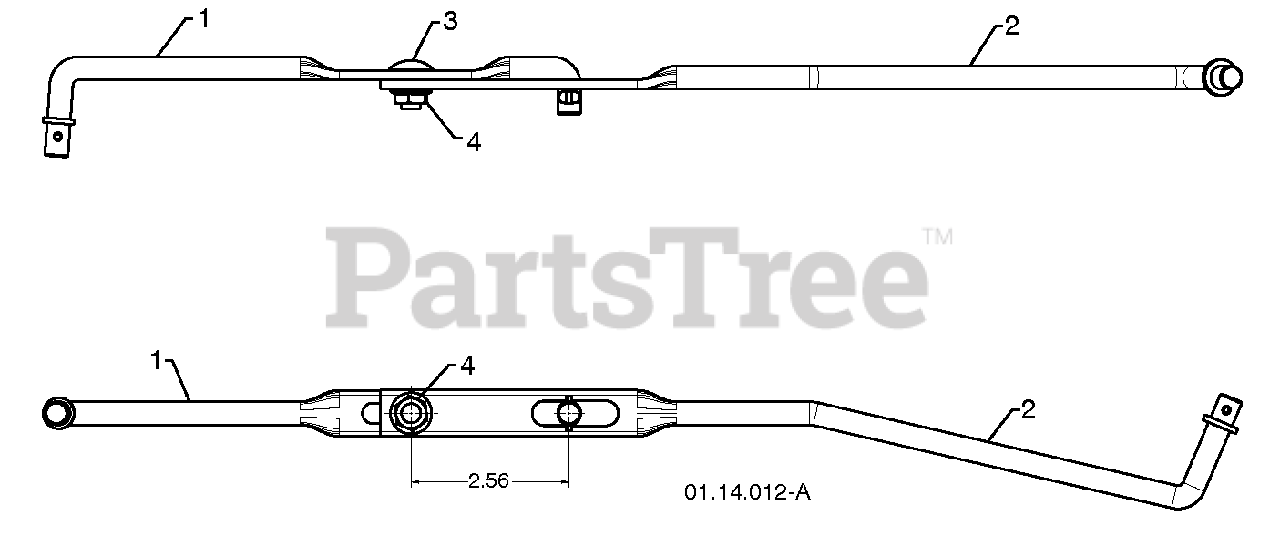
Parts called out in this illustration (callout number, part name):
1	SHIFTER ROD TOP
2	SHIFTER ROD BOTTOM
3	CARRIAGE BOLT 5/16-18 X .75
4	NUT 5/16-18
